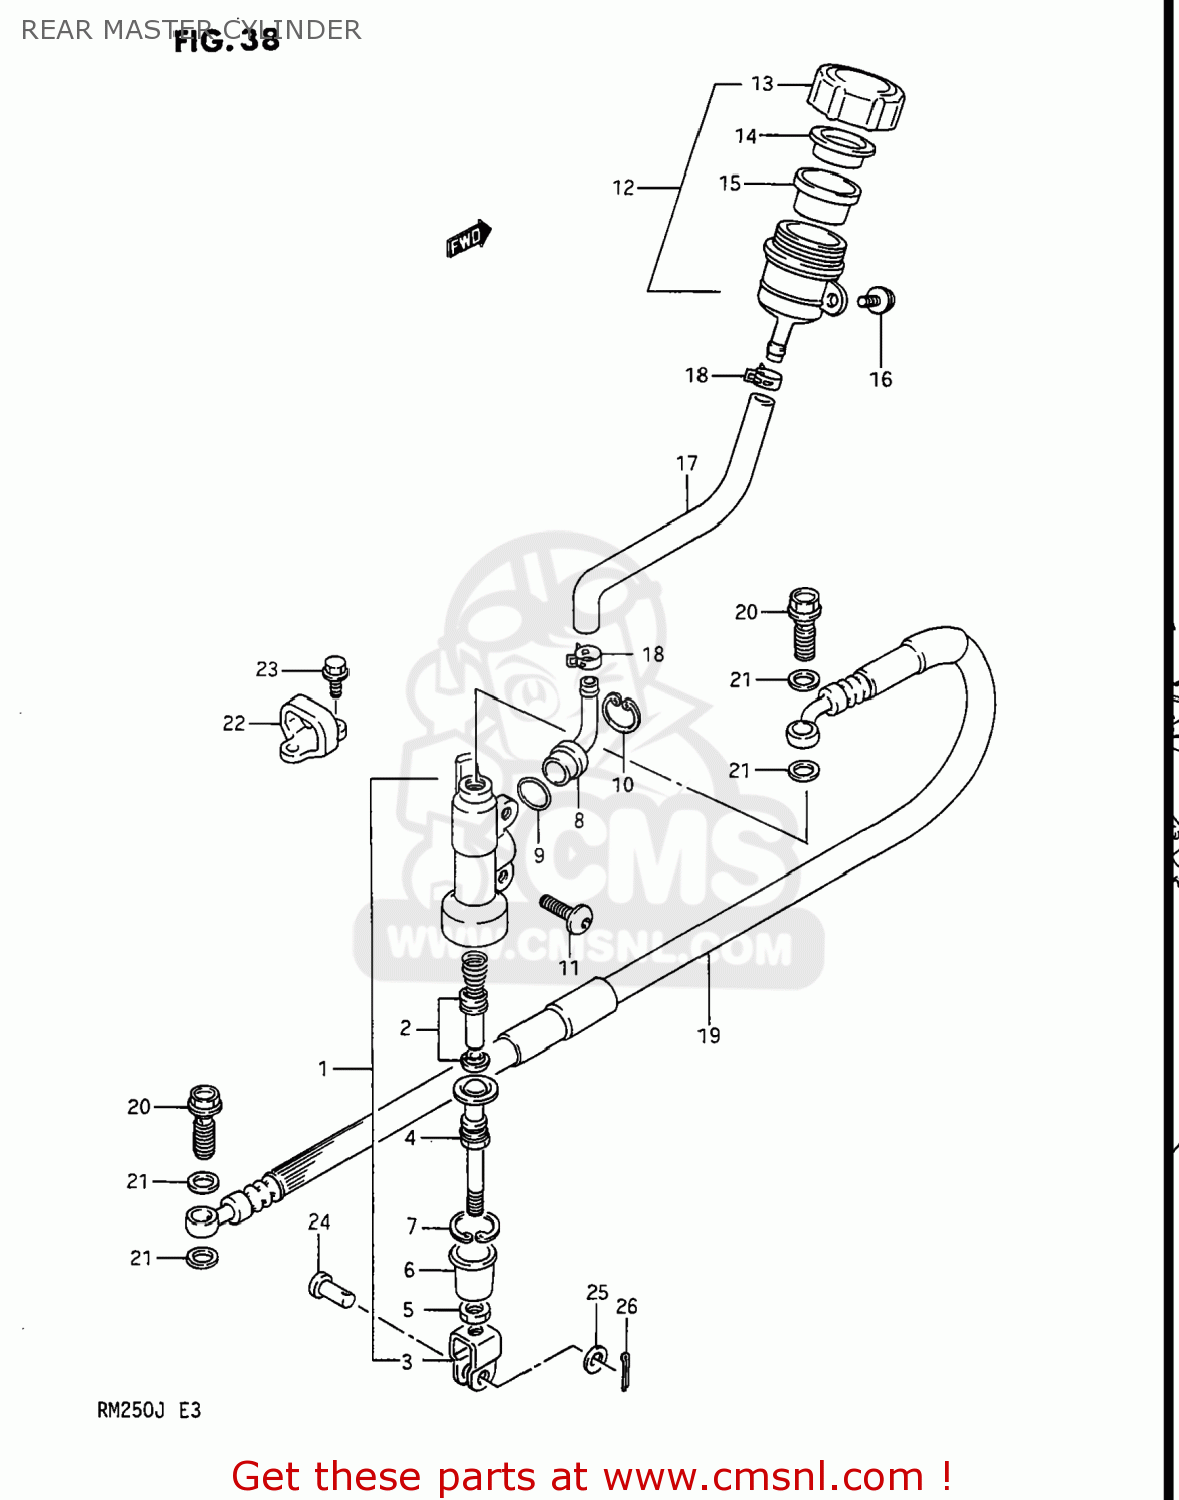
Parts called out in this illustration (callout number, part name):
1	CYLINDER ASSEMBLY,REAR MASTER
2	PISTON/CUP SET
3	YOKE
4	ROD,PUSH
5	NUT
6	BOOT
7	CIRCLIP
8	CONNECTOR
9	O RING
10	CIRCLIP
11	BOLT(6X18)
12	TANK ASSEMBLY,RESERVOIR
13	CAP
14	PLATE
15	DIAPHRAGM
16	BOLT
17	HOSE,RESERVOIR TANK
18	CLAMP,RESERVOIR HOSE
19	HOSE,REAR BRAKE
20	BOLT UNION
21	WASHER(10X15X1.5)
22	GUIDE,RR BRAKE HOSE
23	SCREW(5X10)
24	PIN(8X20)
25	WASHER(8.5X13X1.6)
26	PIN
